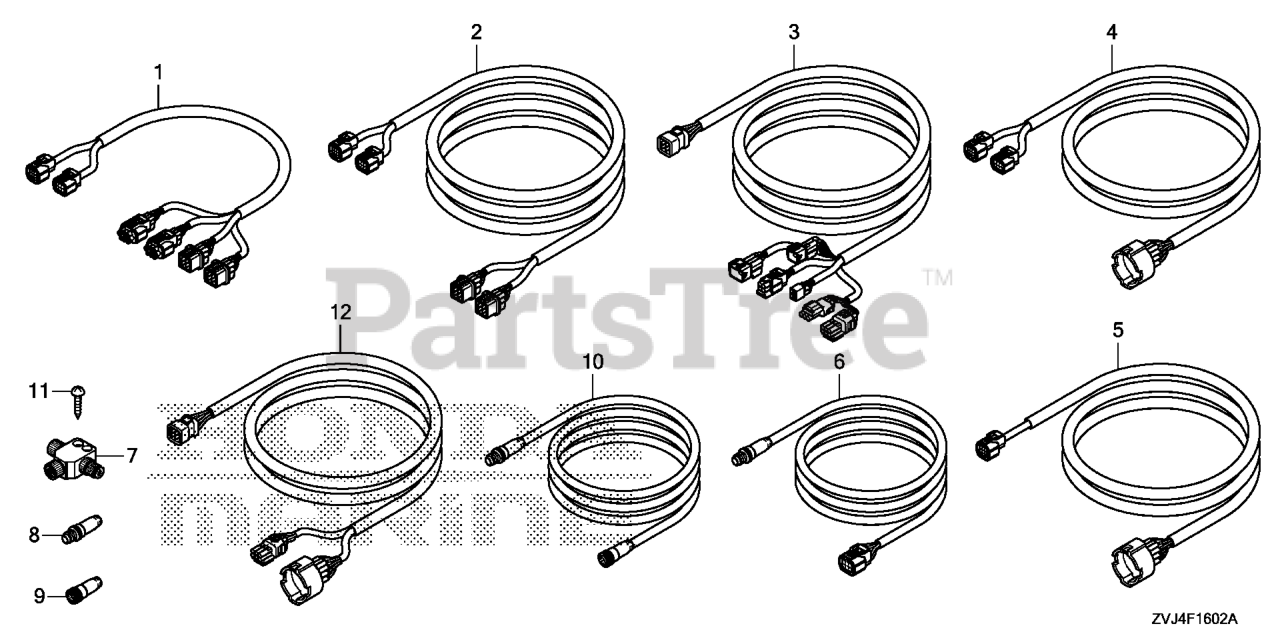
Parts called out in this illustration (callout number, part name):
1	CABLE ASSY., BRANCH
2	CABLE ASSY., TRUNK (30FT) (DBW)
3	CABLE ASSY., PANEL INDICATOR (30FT)
5	CABLE ASSY., ENGINE DROP (10FT)
6	CABLE ASSY., INTERFACE (16FT)
6	CABLE ASSY., INTERFACE (6FT)
7	CONNECTOR (T)
8	TERMINATOR (M)
9	TERMINATOR (F)
10	CABLE ASSY., NETWORK (6FT)
10	CABLE ASSY., NETWORK (49FT)
11	SCREW, TAPPING (4X25)
12	CABLE ASSY., CONVERSION (6FT)
12	CABLE ASSY. (6FT)
12	CABLE ASSY., CONVERSION (10FT)
12	CABLE ASSY. (10FT)
